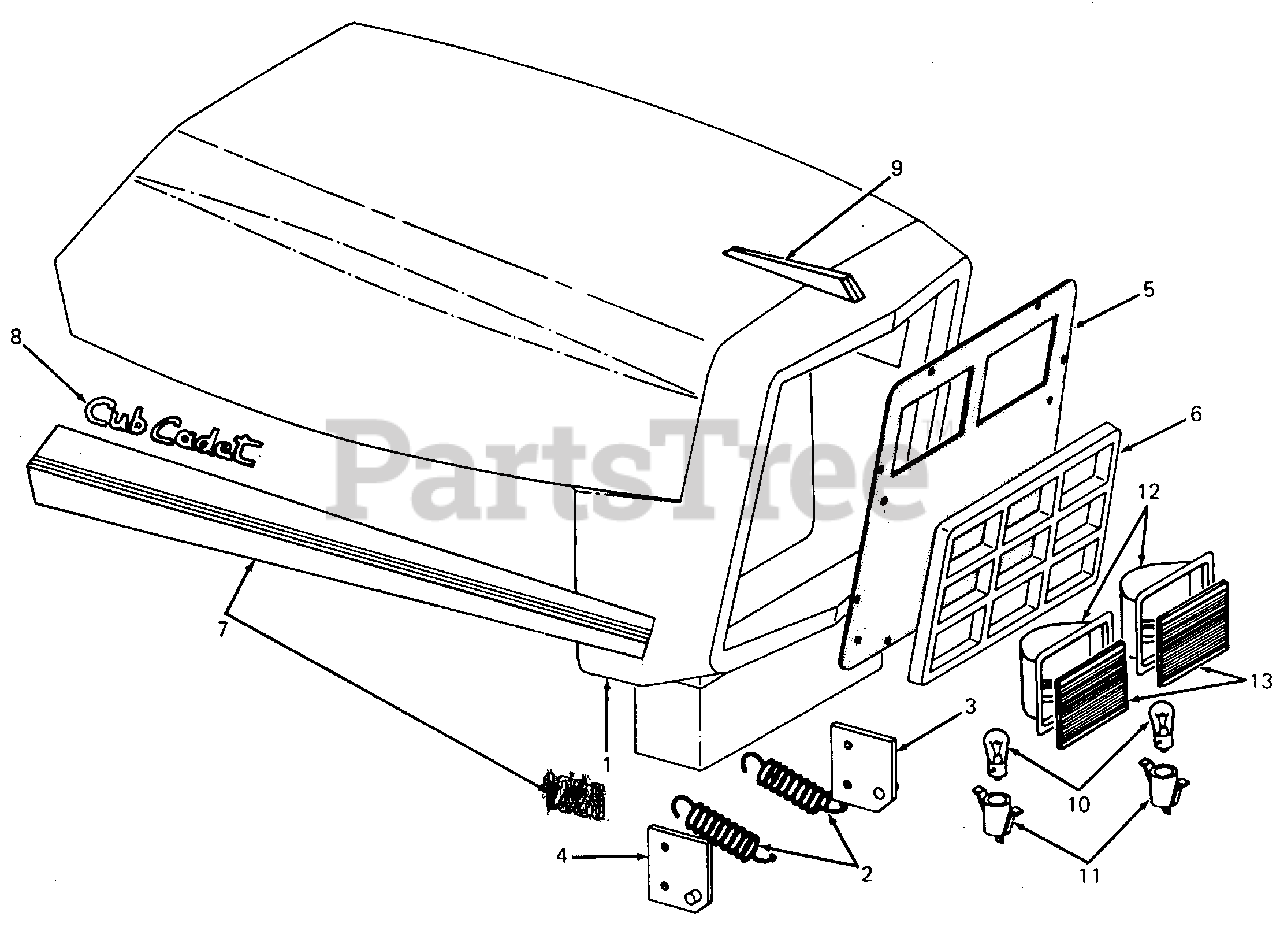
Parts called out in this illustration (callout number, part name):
1	Hood & Grille Assy
2	Spring, Extension
3	Plate, Hood LH
4	Plate, Hood RH
6	Insert, Grille
7	Graphic, Hood Decal Set
8	Graphic, Cub Cadet Script w/Studs
9	Ornament, Hood
10	Bulb, 12V GE-1141
11	Socket, Twist Lock Lamp
12	Housing, Headlight
13	Lens, Sq-Headlight
